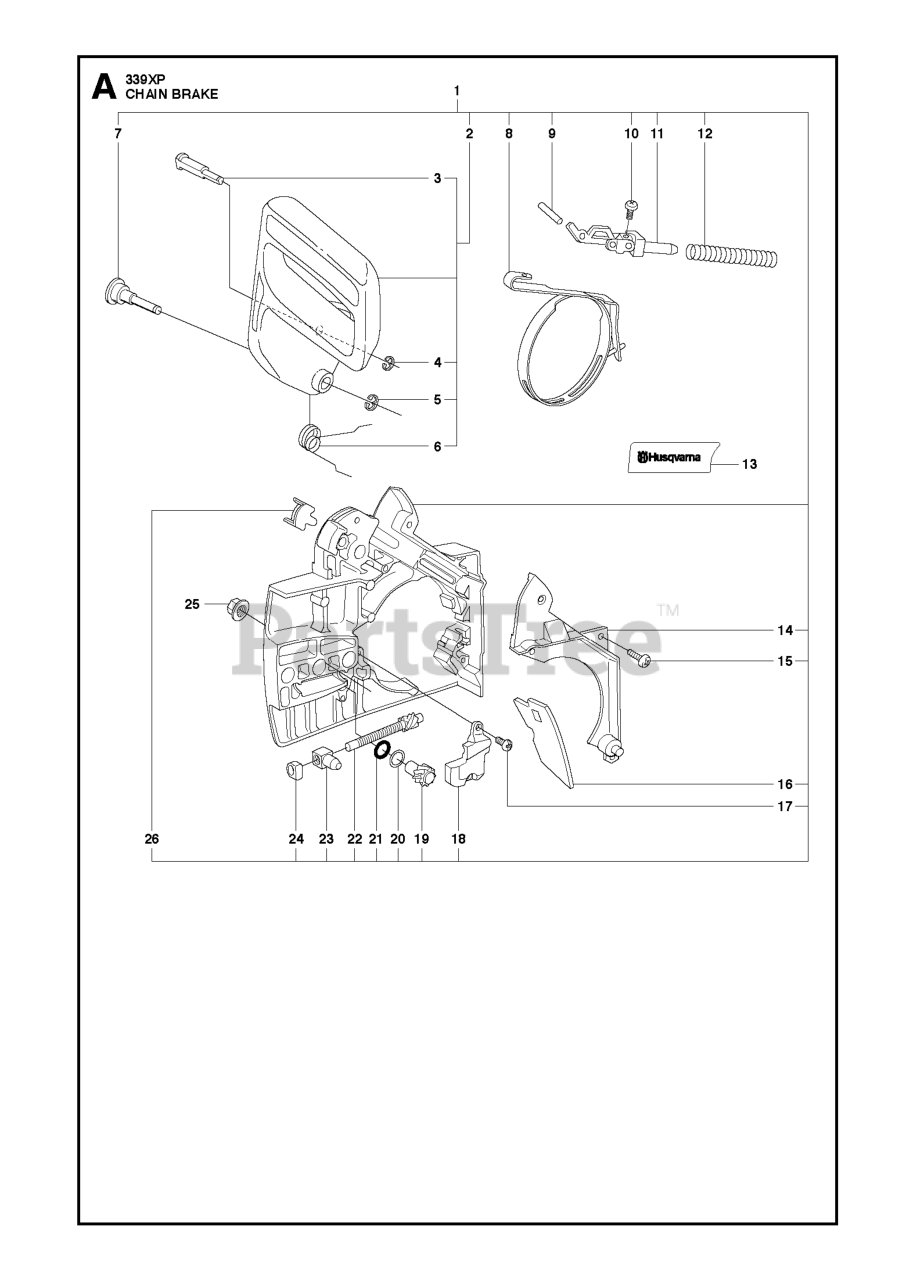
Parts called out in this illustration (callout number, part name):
1	CHAIN BRAKE ASSY
2	HAND GUARD
6	POSITION SPRING
7	SHAFT PIVOT
8	BRAKE BAND ASSY
11	KNEE-JOINT
12	SPRING
19	WORM WHEEL
23	PIN BAR ADJUSTING
25	NUT M8 FLANGE
